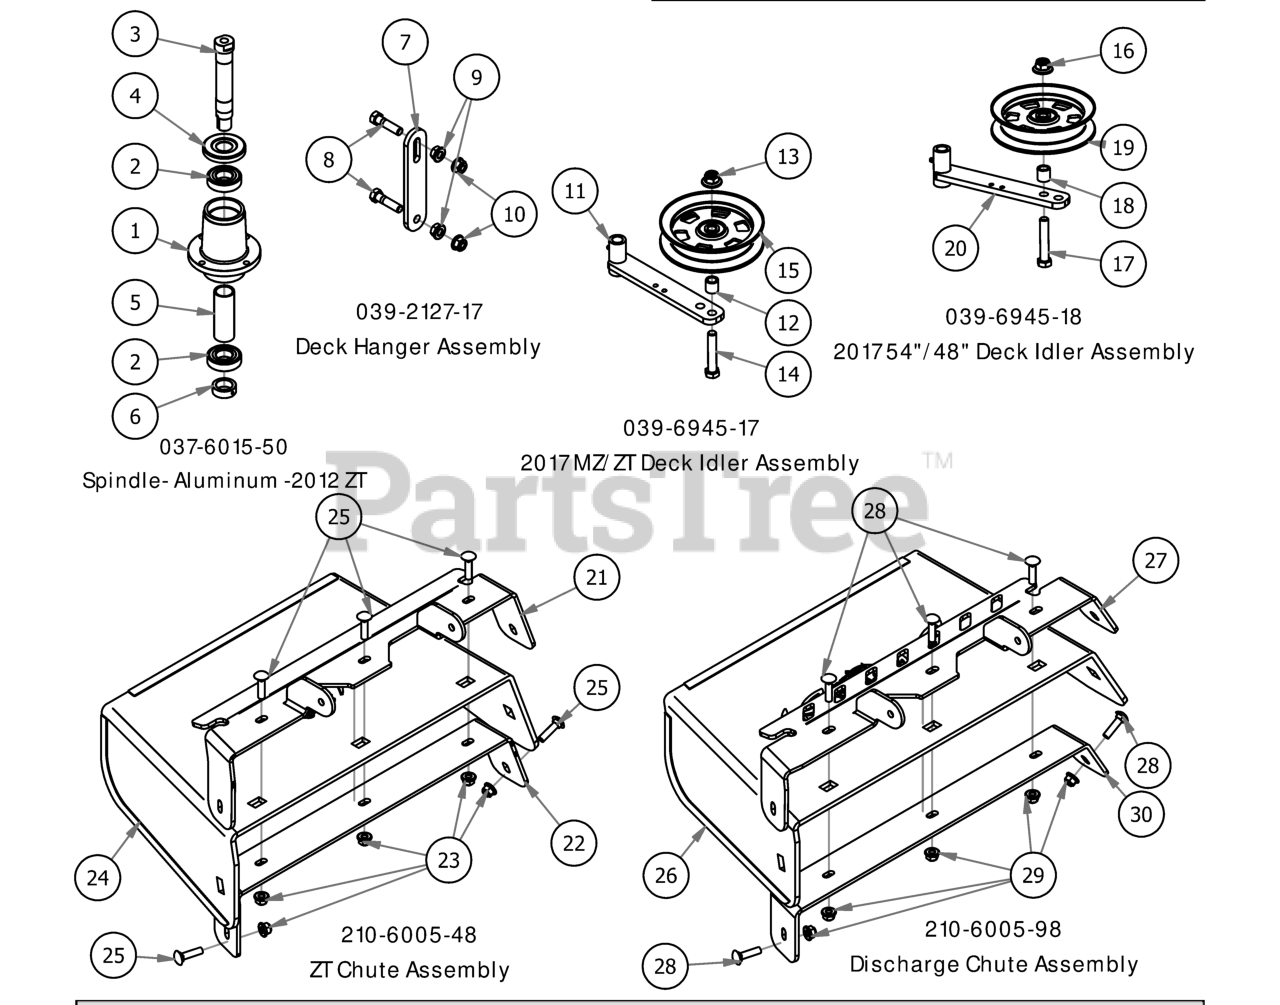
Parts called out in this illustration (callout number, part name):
1	Aluminum Spindle Housing -2010
2	Spindle Bearing, 2004 and up
3	Short Spindle Shaft w/Locking
4	Dust Cover
5	Tube Spacer for Spindle Shaft
6	Collar Spacer - Top of Spindle
7	2017 MZ/ZT Deck Hanger
8	3/8" x 1 1/2" Hex Bolt
9	3/8" Flange Nut
10	3/8" Nylock Flange Nut
11	Deck Idler
12	Spacer 3/4 OD x 1/2 ID x 3\4 Length
13	1/2-13 Nylon Flange Nut
14	1/2" x 2 3/4" Hex Bolt
15	5" Idler Pully
16	1/2-13 Nylon Flange Nut
17	1/2" x 2 3/4" Hex Bolt
18	Spacer 3/4 OD x 1/2 ID x 3\4 Length
19	5" Idler Pully
20	Deck Idler
21	Discharge Upper Chute Bracket
22	Discharge Lower Chute Bracket
23	5/16" Nylon Flange Nut
24	Rubber Discharge Chute
25	5/16" x 1 1/4" Carriage Bolt
26	Rubber Discharge Chute
27	60" Discharge Chute Upper Hanger
28	5/16" x 1 1/4" Carriage Bolt
29	5/16" Nylon Flange Nut
30	60" Discharge Lower Bracket
